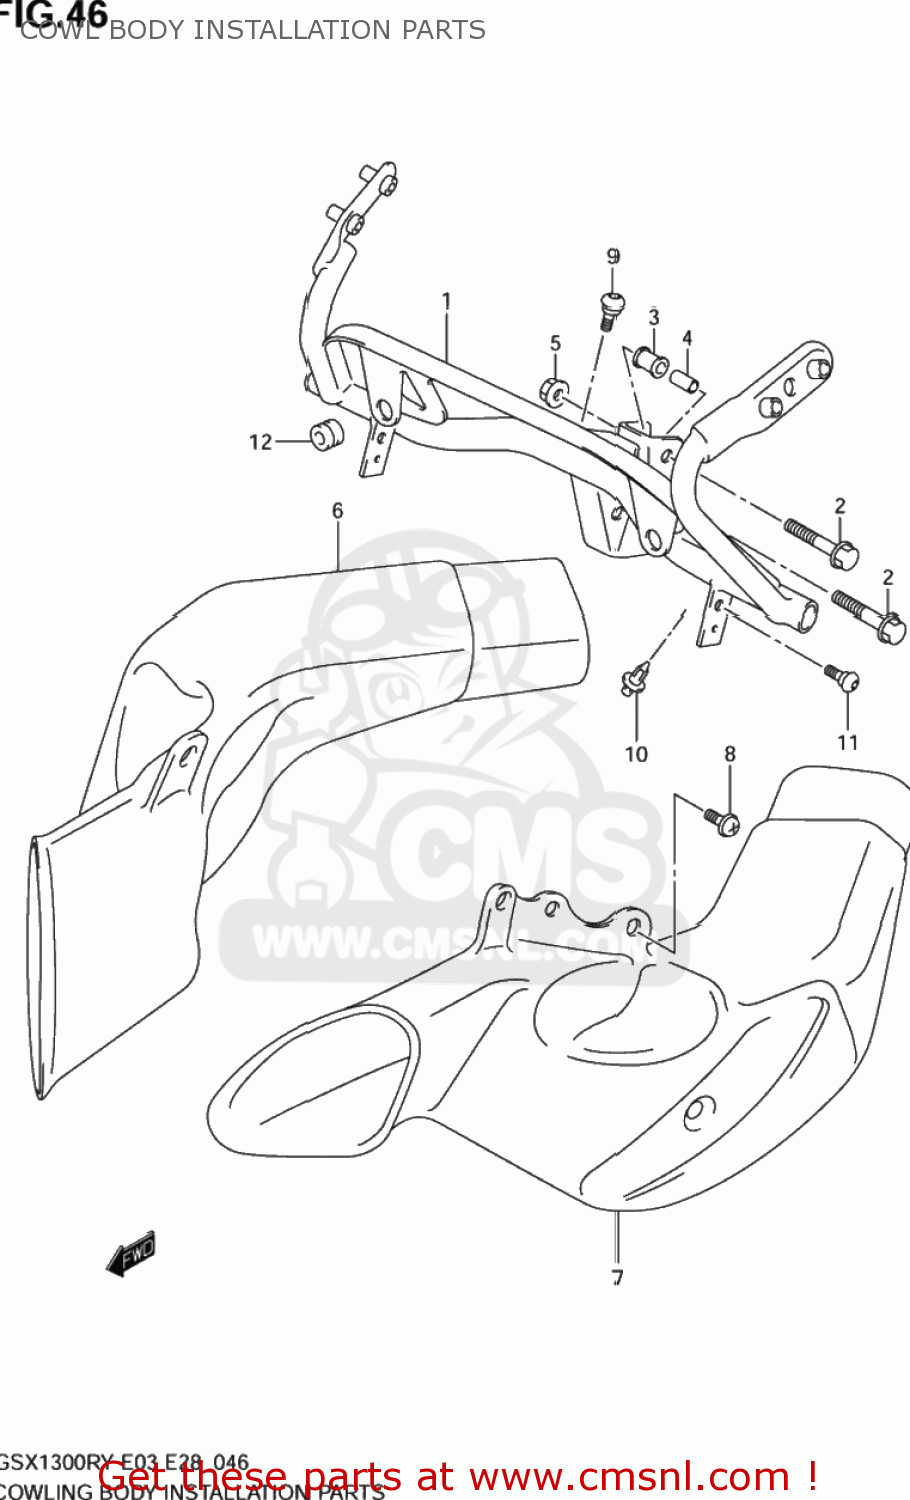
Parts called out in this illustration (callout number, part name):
1	BRACE,COWLING
2	BOLT
3	CUSHION,COWLING BRACE
4	SPACER
5	NUT
6	PIPE,AIR INTAKE,R
7	PIPE,AIR INTAKE,L
8	SCREW(5X14)
9	SCREW(5X16)
10	CLIP(BLACK)
11	SCREW(5X16)
12	CUSHION
